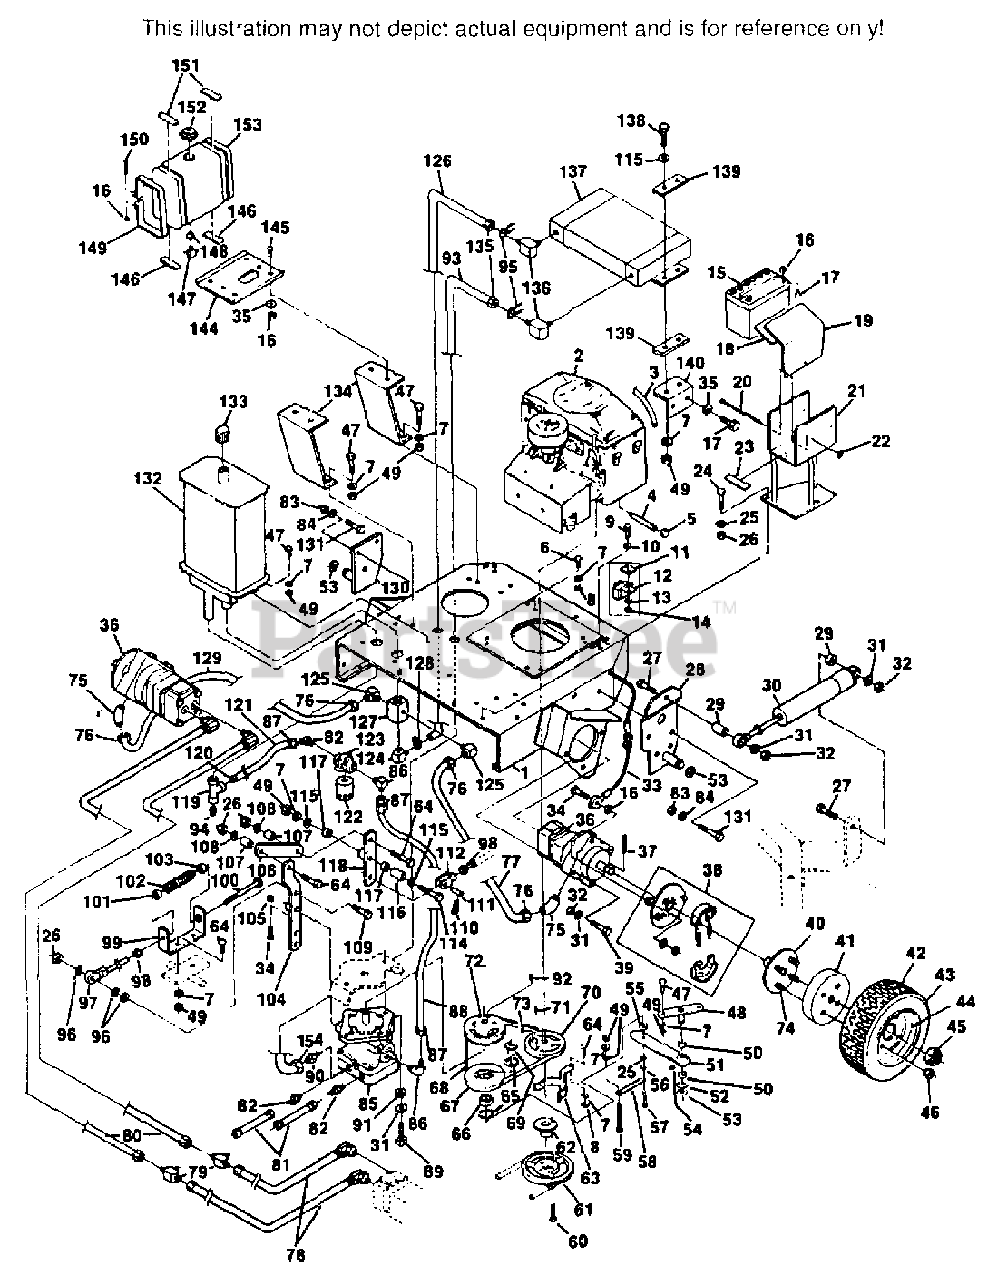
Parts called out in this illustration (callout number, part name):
1	ENGINE DECK
2	ENGINE, 20 HP KOHLER(MV20S PS-57511)
3	HOSE, FUEL
4	OIL DRAIN EXTENSION(INCLUDES PLUG)
7	LOCKWASHER, 5/16 SPRING
8	HEX NUT, ELASTIC STOP LOCK, 5/16-18
11	STOP, MOWER ENGAGE
12	SWITCH, MOWER ENGAGE
15	BATTERY
18	INSULATION, BATTERY COVER
19	BATTERY COVER
21	BATTERY BOX
22	WING NUT, 1/4-20
23	PAD, BATTERY SUPPORT
25	LOCKWASHER, 3/8 SPRING
28	HITCH BRACKET, LH
29	SLEEVE, SHOCK ABSORBER MOUNT
30	SHOCK ABSORBER
31	LOCKWASHER, 1/2 SPRING
33	PARKING BRAKE CABLE ASSEMBLY - LH
35	LOCKWASHER, 1/4 SPRING
36	MOTOR, WHITE(INCLUDES ITEM 45, LESS BRAKE
38	PARKING BRAKE ASSEMBLY
40	HUB ASSEMBLY(INCLUDES BOLTS)
41	BRAKE DRUM
42	RIM AND TIRE ASSEMBLY
43	TIRE, 20 X 8.00-10, 4 PLY
44	RIM ONLY
45	CASTLE NUT, 1.0-20 UNEF
46	WHEEL NUT
48	IDLER PIVOT BASE
50	BRONZE BUSHING
51	PUMP IDLER ARM(INCLUDES(2) 50 AND(1) 54)
52	FLAT WASHER, 3/4(49/64 X 1-1/4 X .035)
53	RETAINING RING, 3/4 "E"
54	GREASE FITTING
55	SPACER, IDLER
58	SPRING, TRACTION DRIVE BELT
61	PULLEY, BLADE DRIVE(INCLUDES 60 AND 62)
62	HUB, TAPERED
63	BELT GUIDE
65	RETAINING RING, 1-9/16 INTERNAL
66	BEARING, IDLER PULLEY
67	PULLEY, IDLER - TRACTION DRIVE(INCL. 65,
68	BELT, PUMP DRIVE
69	SLEEVE, IDLER(TAPPED)
70	PULLEY, ENGINE - PUMP
71	KEY, 1/4 X 1/4 X 2-1/2(PLATED)
72	PULLEY, PUMP INPUT
73	5/16-18 X 3/8" HEX SOCKET SET SCREW
74	BOLT, HUB
75	ELBOW, 45 DEG. MALE, JIC TO "O" RING
76	COUPLING, SAE FLARE SWIVEL, PUSH ON HOSE END
77	HOSE, PUSH ON 1/4 ID - LH
78	HOSE ASSEMBLY - LH MOTOR
79	TUBE TEE
80	HOSE ASSEMBLY - RH MOTOR
81	TUBE ASSEMBLY
82	ELBOW, 45 DEG. MALE, JIC TO "O" RING
84	LOCKWASHER, 7/16 SPRING
85	PUMP, SUNSTRAND
86	ELBOW, 90 DEG., JIC TO "O" RING
87	COUPLING, SAE FLARE SWIVEL, PUSH ON HOSE END
88	HOSE, 1/2 ID, OIL FILTER TO PUMP
89	CAPSCREW, 1/2-13 X 1-1/4 SOCKET HD.
90	UNION, TUBE JIC TO "O" RING
92	KEY, 3/16 X 5/8 WOODRUFF #61
93	HOSE
94	PIPE PLUG, 1/2 NPT - MAGNETIC
95	CORBIN CLAMP - 1"
97	ROD END
99	RETAINER, NEUTRAL SPRING
100	BOLT, HEX HD., 3/8-24 X 6-3/4 SPECIAL
101	BUSHING, SPRING KEEPER, SHORT
102	SPRING, NEUTRAL RETURN
103	BUSHING, SPRING KEEPER, LONG
104	CONTROL ARM, PUMP
105	HEX NUT, ELASTIC STOP LOCK, 1/4-20
106	LINK, SPEED CONTROL
107	SLEEVE, PUMP CONTROL LINK
108	FLAT WASHER, 3/8(25/64 X 15/16 X 12 GA.)
110	HAIR PIN COTTER, SMALL
111	CLEVIS PIN
112	CLEVIS, PUMP CONTROL
116	SLEEVE, CONTROL ARM
117	BRONZE BUSHING
118	CONTROL ARM, BELLCRANK(INCLUDES(2) 117)
119	PIPE TEE, 1/2 NPT
120	COUPLING, STRAIGHT MALE, PIPE NPT, PUSH ON
121	HOSE, TEE TO OIL FILTER
122	OIL FILTER(SPECIAL)
123	HEAD, OIL FILTER
124	ELBOW, 90 DEG. MALE, PIPE NPT, PUSH ON HOSE
125	ELBOW, 90 DEG. MALE, JIC TO NPT
126	HOSE
127	MANIFOLD
128	CLAMP, WORM DRIVE
129	HOSE, PUSH ON, 1/4 ID - RH
130	HITCH BRACKET - RH
132	OIL RESEVOIR
133	CAP, OIL RESEVOIR
134	MOUNTING BRACKET, FUEL TANK
135	COUPLING
136	ELBOW 90 DEG
137	RADIATOR, OIL COOLER
139	PAD, RUBBER
140	BRACKET, RADIATOR MOUNTING
144	SUPPORT, FUEL TANK
146	PAD, FUEL TANK SUPPORT
147	FUEL SHUT OFF VALVE
148	BUSHING, FUEL TANK VALVE
149	STRAP, FUEL TANK
151	PAD, FUEL TANK STRAP
152	CAP, FUEL TANK
153	FUEL TANK ASSEMBLY(INCLUDES 147, 148)
154	COUPLING, 3/4-16 SAE FLARE SWIVEL, 5/8"
